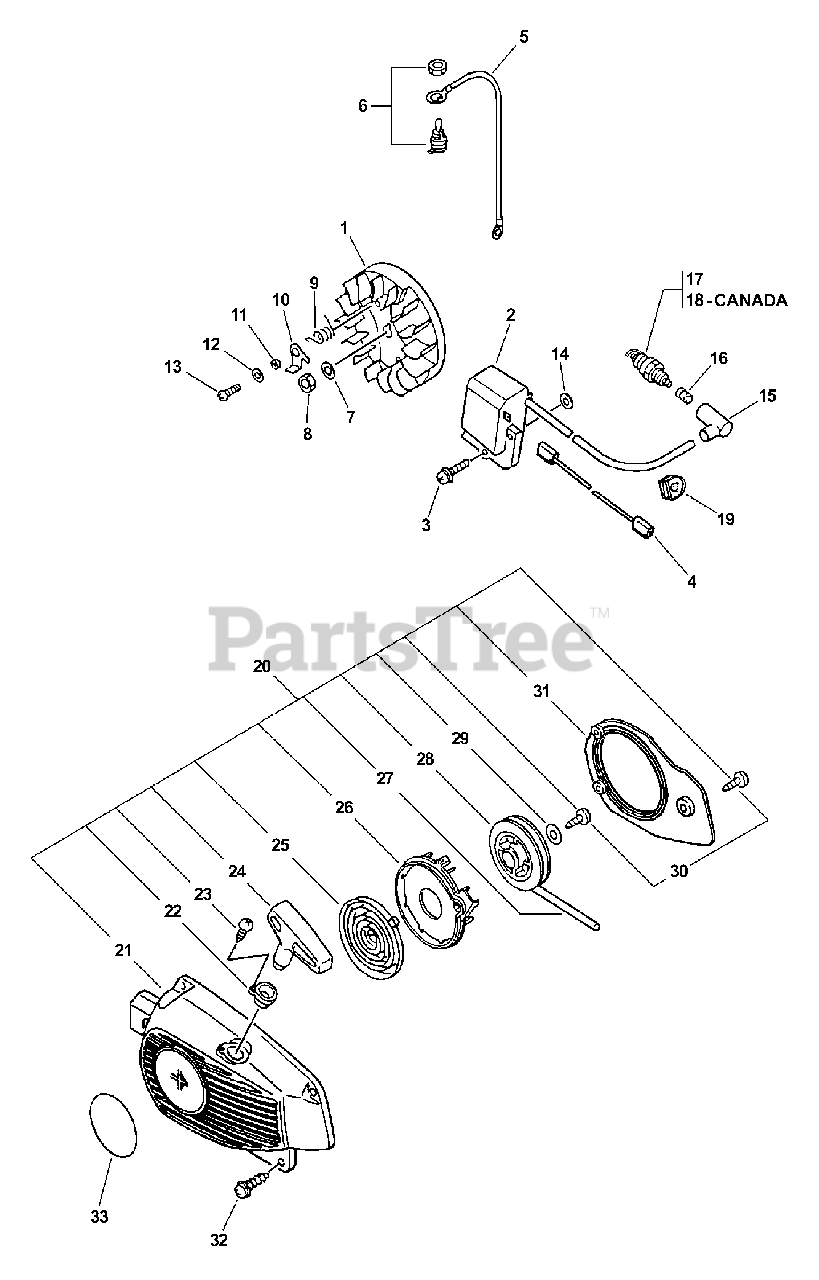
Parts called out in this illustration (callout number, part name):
1	FLYWHEEL
2	COIL, IGNITION
3	SCREW 5×20
3	SCREW 5×22
4	LEAD - IGNITION L= 95
5	LEAD - GROUND L= 100
6	SWITCH, ON-OFF
7	WASHER 8.5×16×1.2
8	NUT M8
9	SPRING, TORSION
10	PAWL, STARTER
11	SPACER 5.2×8×2.1
12	WASHER 5.5×12×0.8
13	SCREW 5×12
14	WASHER 5.2×12×3
15	CAP, SPARK PLUG
16	TERMINAL, SPARK PLUG
17	SPARK PLUG - BPM7A
18	SPARK PLUG - BPMR7A
19	GROMMET
20	STARTER ASSY
21	CASE, STARTER
22	GUIDE, ROPE
23	SCREW 3×14
24	GRIP, STARTER
25	SPRING, RECOIL
26	PLATE, STARTER
27	ROPE, STARTER 3.0×850
28	REEL, ROPE
29	WASHER 4.1×15.5×1T
30	SCREW 4×14
32	SCREW 4×16
33	LABEL, ECHO
